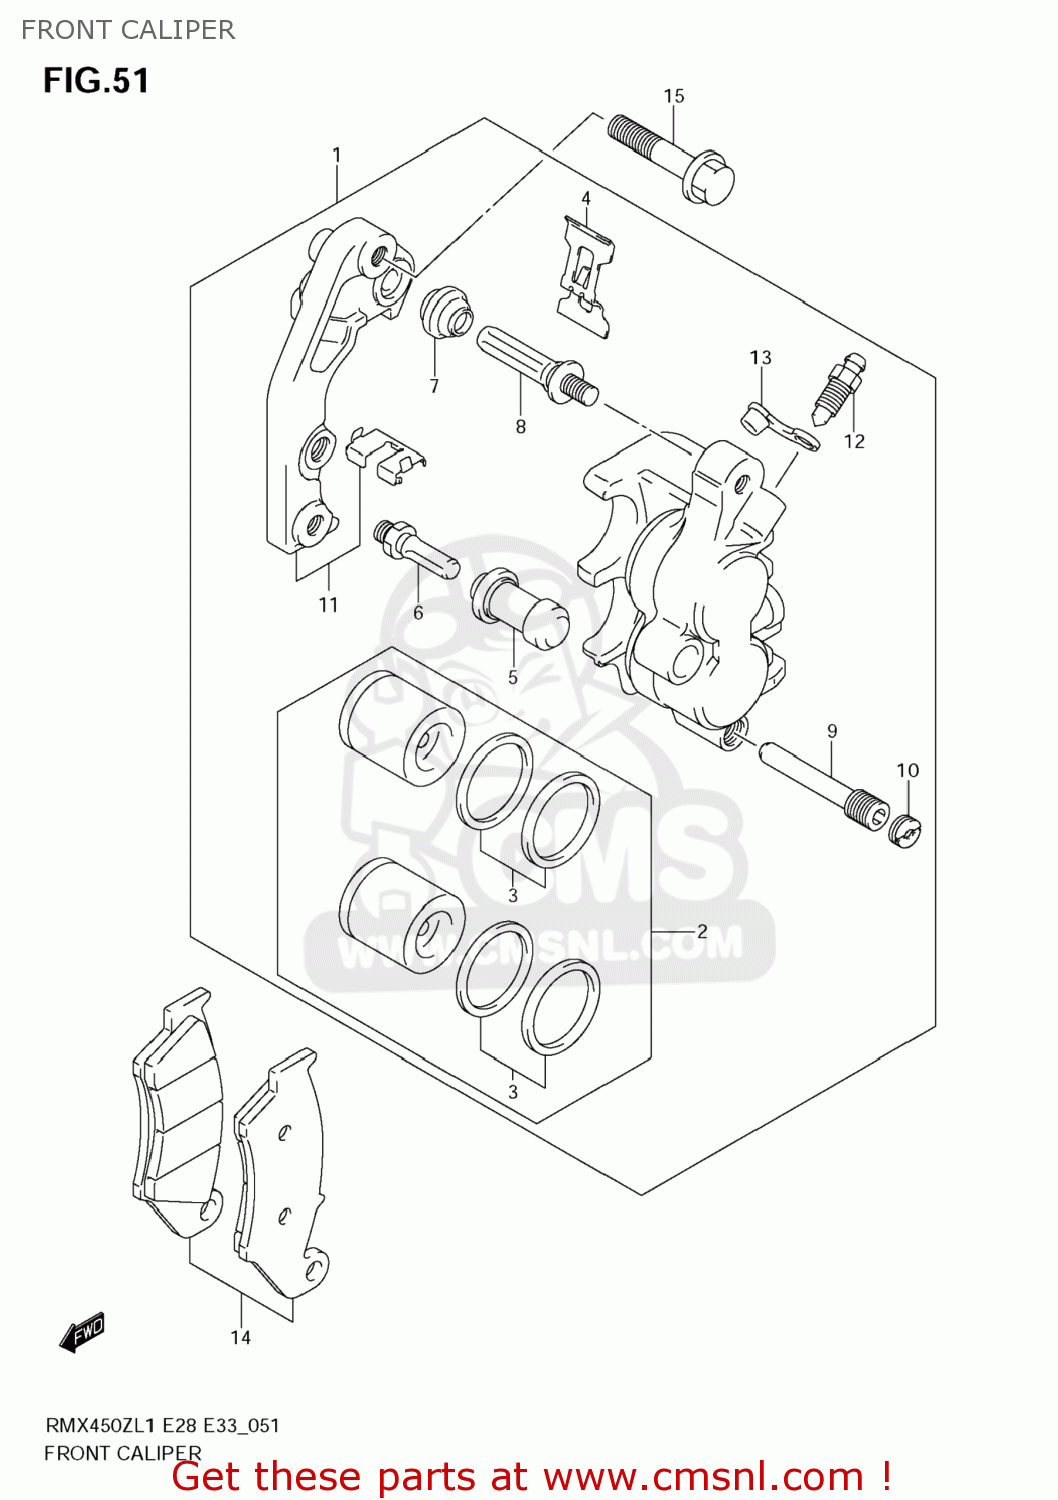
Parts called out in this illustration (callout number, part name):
1	CALIPER ASSY,FR
2	PISTON SET
3	SEAL SET,PISTON
4	SPRING,PAD
5	BOOT
6	BOLT
7	BOOT
8	PIN
9	PIN,HANGER
10	PLUG,PIN
11	BRACKET
12	BLEEDER
13	CAP,BLEEDER
14	PAD SET (NAS)
15	BOLT(8X40)
